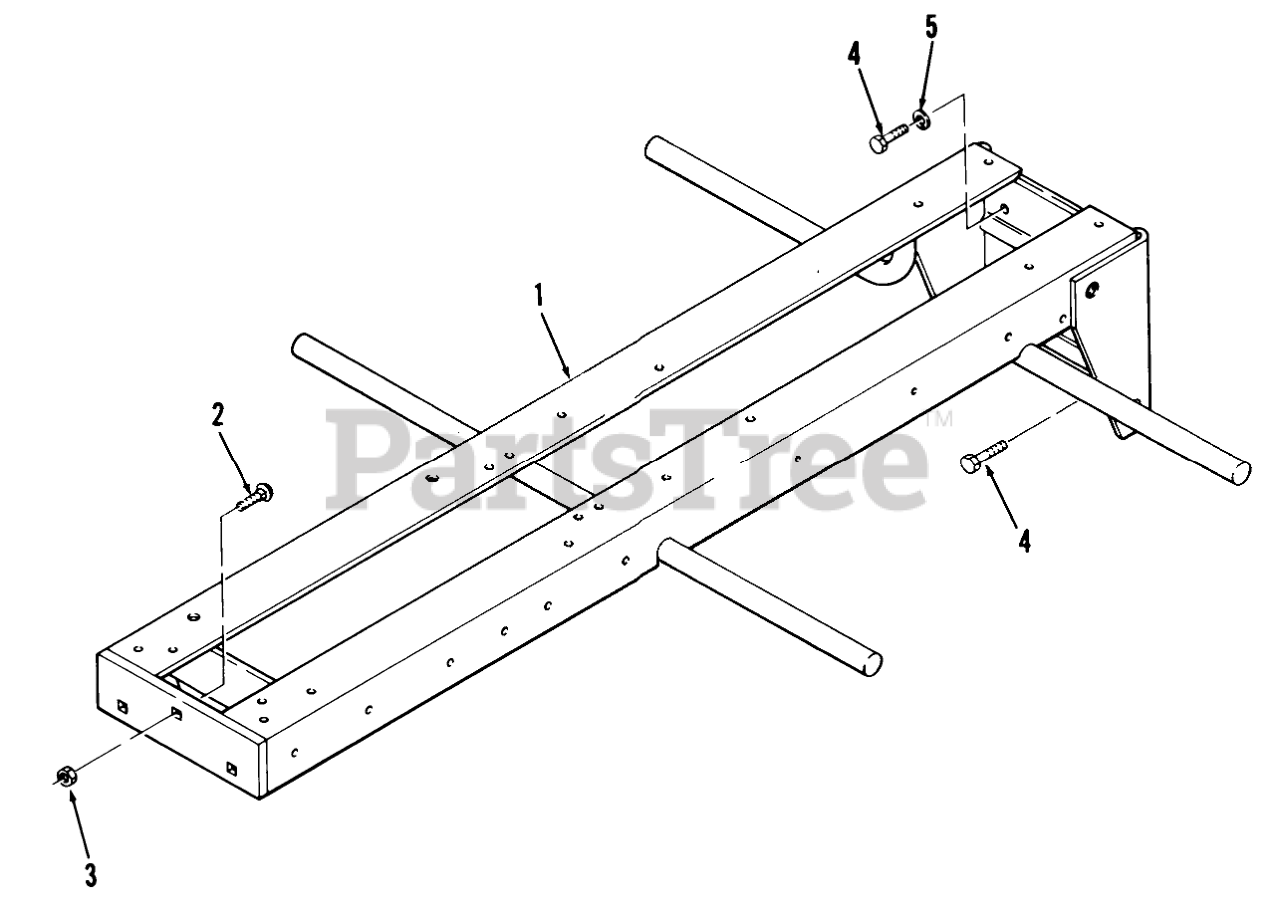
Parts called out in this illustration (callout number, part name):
1	Frame
2	Bolt
3	Nut
4	Bolt
5	LOCKWASHER
